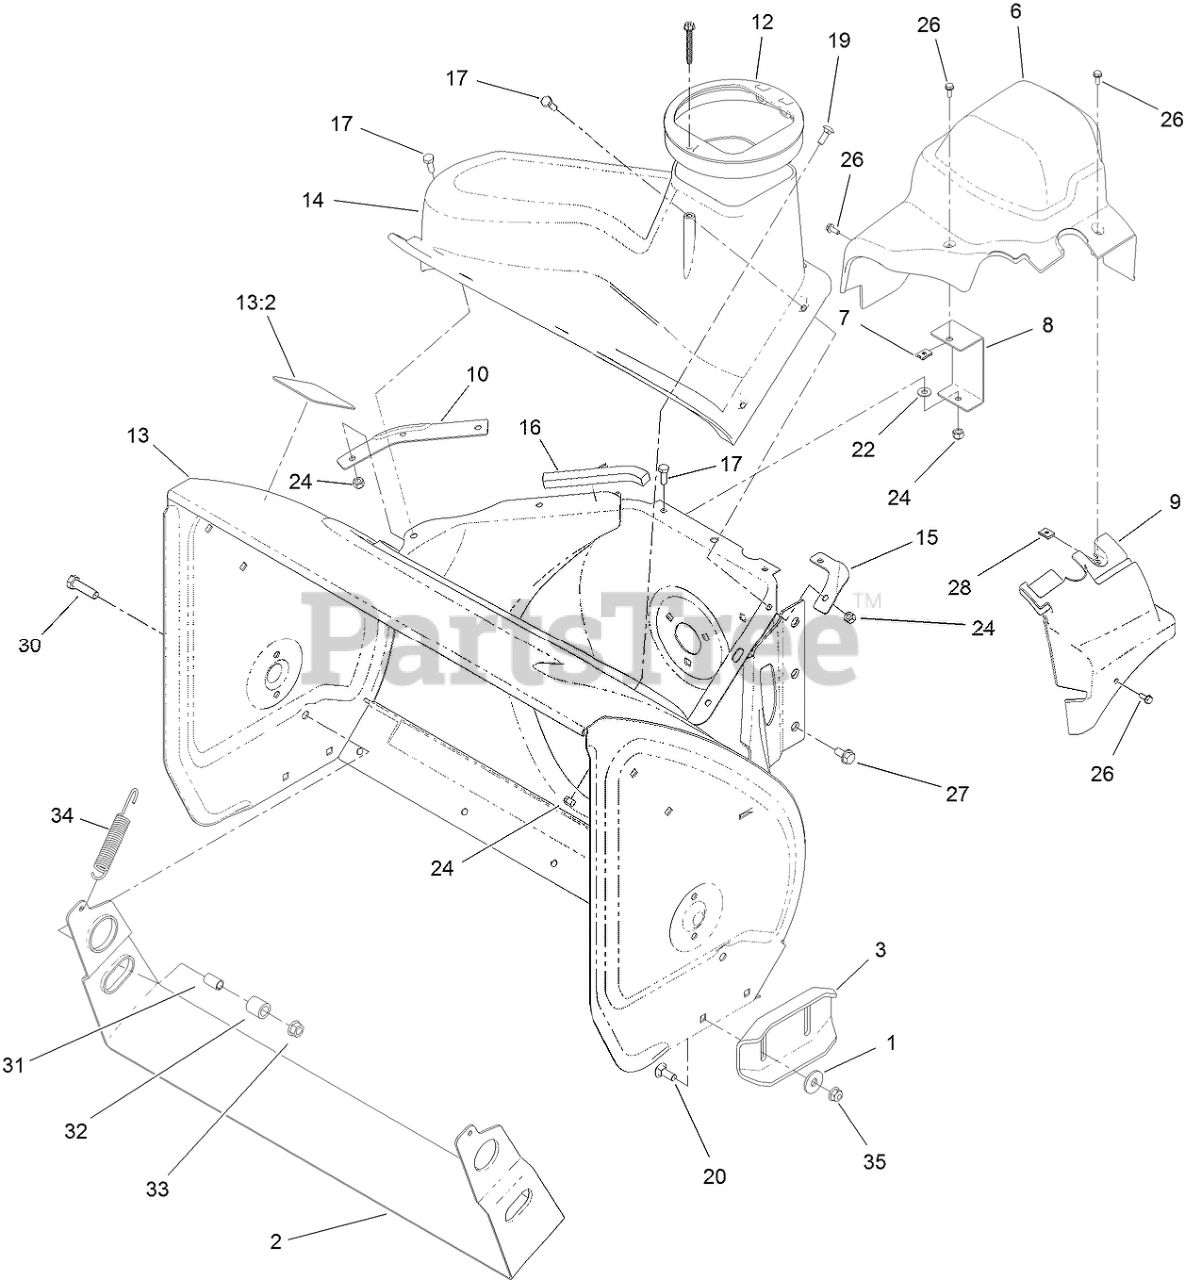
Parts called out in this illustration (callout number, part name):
1	WASHER-FLAT
2	SCRAPER-PIVOTING, 28 INCH
6	COVER-BELT
7	NUT-SPEED
8	BRACKET-COVER, CLIP NUT
9	COVER-EXTENSION, BELT
10	SEAL-FLANGE, COVER
12	GUIDE-CHUTE
13	HOUSING-AUGER, 28 INCH
13:2	DECAL-DANGER, AUGER
16	SEAL-HOUSING
17	SCREW-HH
19	BOLT-CARR
20	BOLT-CARR
22	WASHER-FLAT
24	NUT-HEX
26	SCREW-HWH
27	SCREW-HWHTF
28	NUT-SPEED
30	SCREW-HH
31	SPACER-SCRAPER STOP
32	CUSHION-SCRAPER, STOP
33	NUT-HEX FLG
34	SPRING-SCRAPER
35	NUT-HF
